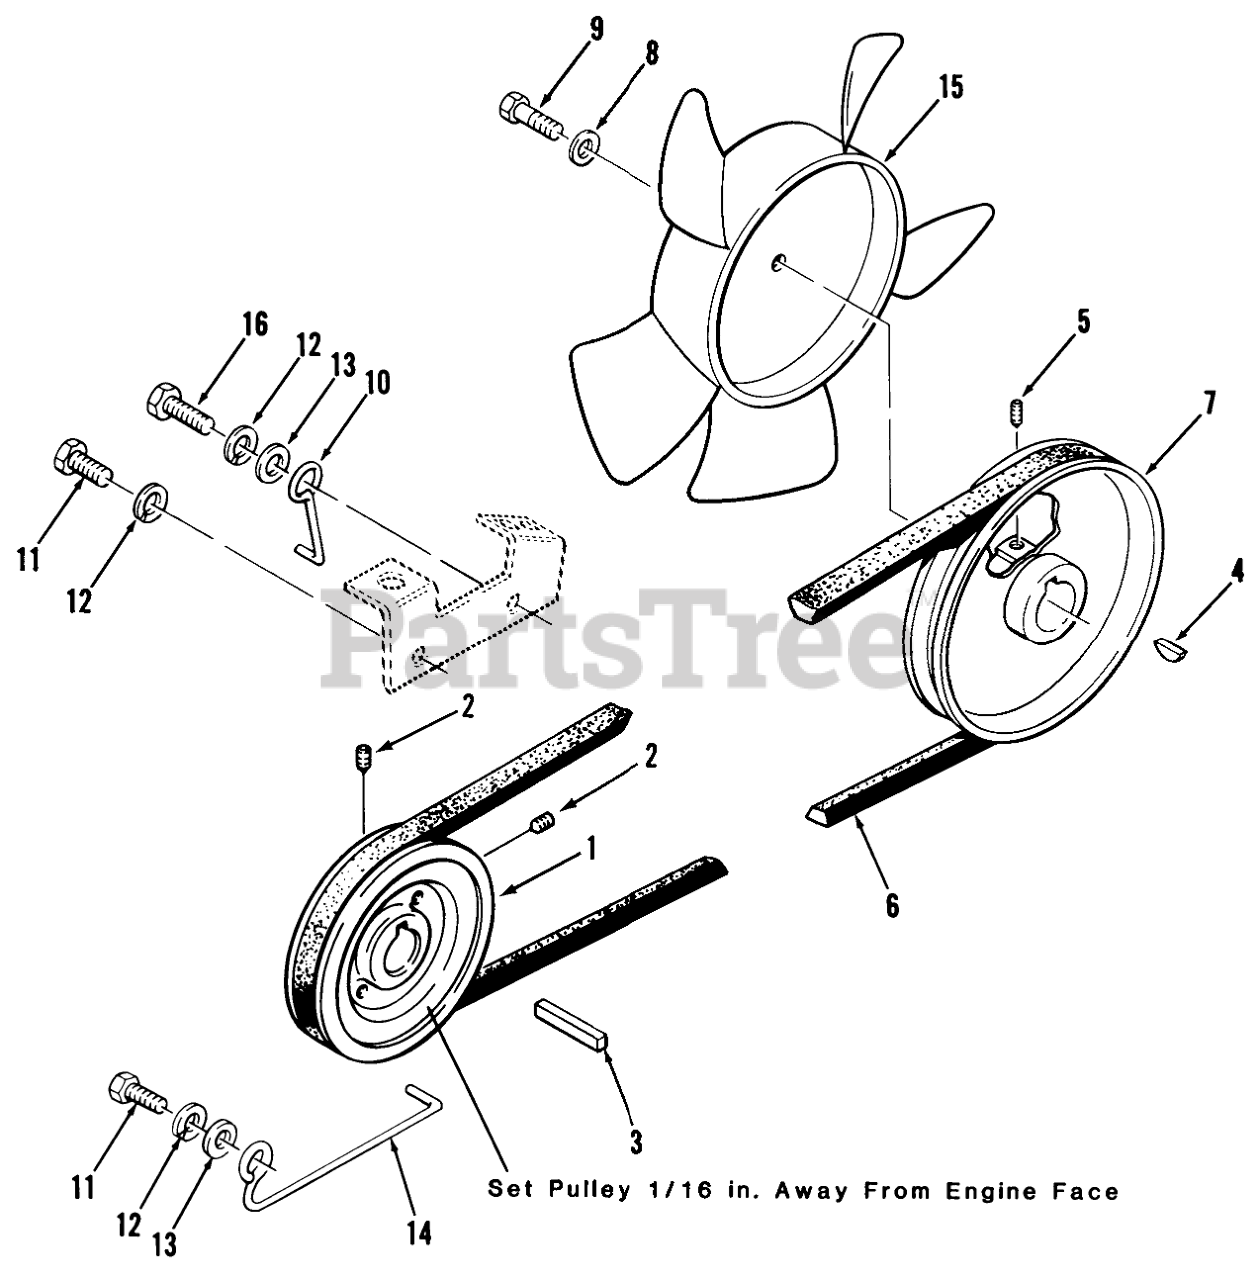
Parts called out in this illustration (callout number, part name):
1	PULLEY
1	PULLEY-ENGINE
2	Set Screw
4	KEY-HI PRO
4	KEY-WOODRUFF
5	Set Screw
6	V BELT
6	Belt-Drive
6	V-BELT TRANS DRIVE
7	PULLEY-TRANSMISSION
7	PULLEY
8	WASHER
9	H H C S
10	Belt Guide-Top
11	BOLT
12	LOCKWASHER
13	Washer
14	GUIDE-BELT
14	Belt Guide-Bottom
15	NYLON FAN-L-CW
16	Bolt
